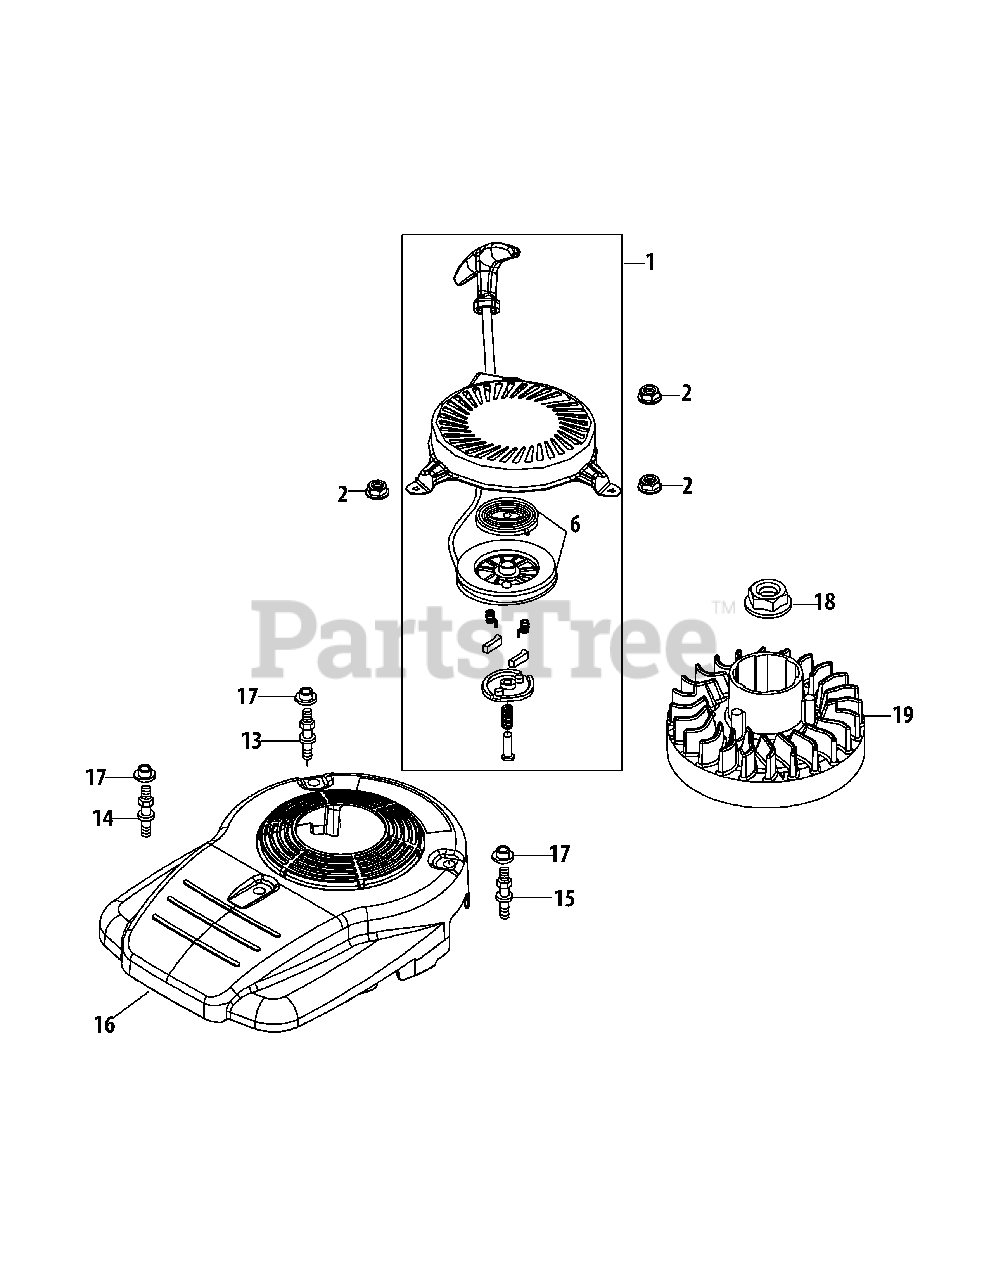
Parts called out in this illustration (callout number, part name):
1	Recoil Starter Assembly
2	Nut M6X10Mm
6	Recoil Pulley & Spring Asm
13	Stud Left/Black
14	Stud Front/Unmarked
15	Stud Right/White
16	Engine Shroud (M0)
17	Engine Shroud Spacer
18	Flywheel Nut M14
19	Flywheel
